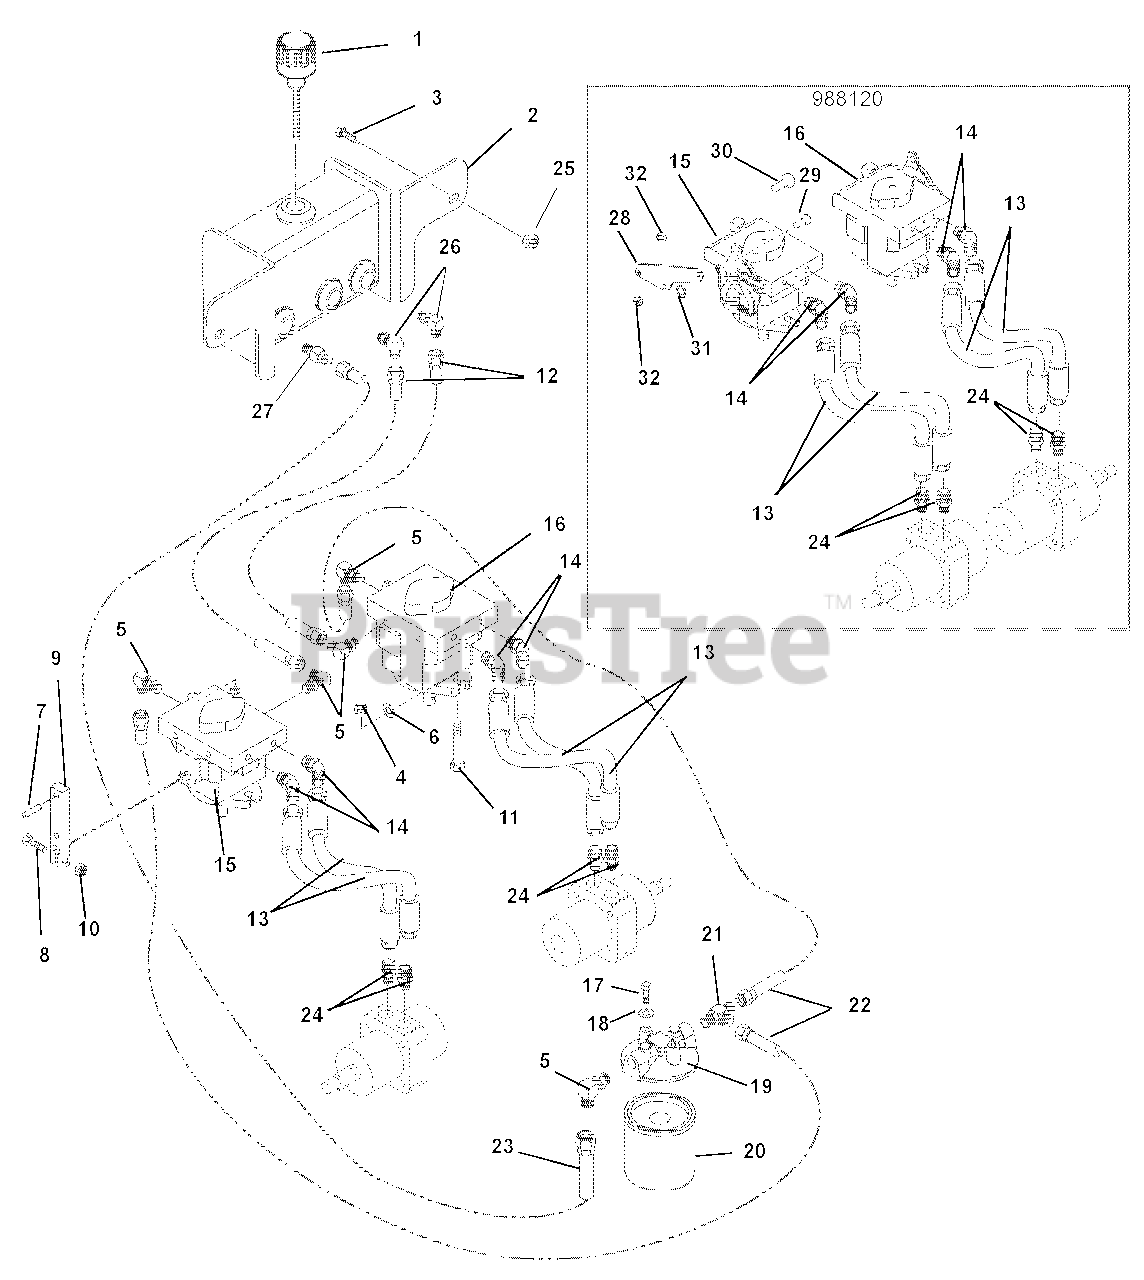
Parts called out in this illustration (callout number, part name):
1	Breather, Dipstick
2	Tank Assembly, Hydraulic
3	Bolt, Hex .38-16 x 1.00 Grade 5
4	Nut, Nylon-Locking .44-14
5	Fitting, Hydraulic
6	Washer, Flat-Steel .43 x 1.00 x .16
7	Pin-Dowel .312 x 1.25 (105, 108, 123, 126)
8	Bolt, Hex .25-20 x 1.25 Grade 5 (105, 108, 123, 126)
9	Arm, Pump Actuating (105, 108, 123, 126)
10	Nut, Locking-Nylon .25-20 (105, 108, 123, 126)
11	Bolt, Hex .44-14 x 1.50 Grade 5
12	Hose, Hydraulic
13	Hose, Hydraulic
14	Fitting, Hydraulic
15	Pump, Hydraulic Right Hand (105, 108, 123, 126)
16	Pump, Hydraulic Left Hand (105, 108, 123, 126)
17	Bolt, Hex .25-20 x .50 Grade 5
18	Washer, Locking .25 x .062 Regular
19	Head, Filter
20	Filter- Oil
21	Fitting, Hydraulic Tee
22	Hose, Hydraulic
23	Hose, Hydraulic
24	Fitting 12MP-6FP Broyhill # TM5406-12-6
25	Nut, Locking-Nylon .38-16
26	Hydraulic, Fitting Elbow
27	Hydraulic, Fitting Straight
28	Bracket, Return to Neutral/Damper (120, 124, 125, 127)
29	Bolt, Hex .31-18 x .50 Grade 5 (120, 124, 125, 127)
30	Bolt, Hex .31-18 x 1.00 Grade 5 (120, 124, 125, 127)
31	Bushing-Sleeve .377 x .624 x .370 (120, 124, 125, 127)
32	Nut, Locking-Center .31-18 (120, 124, 125, 127)
